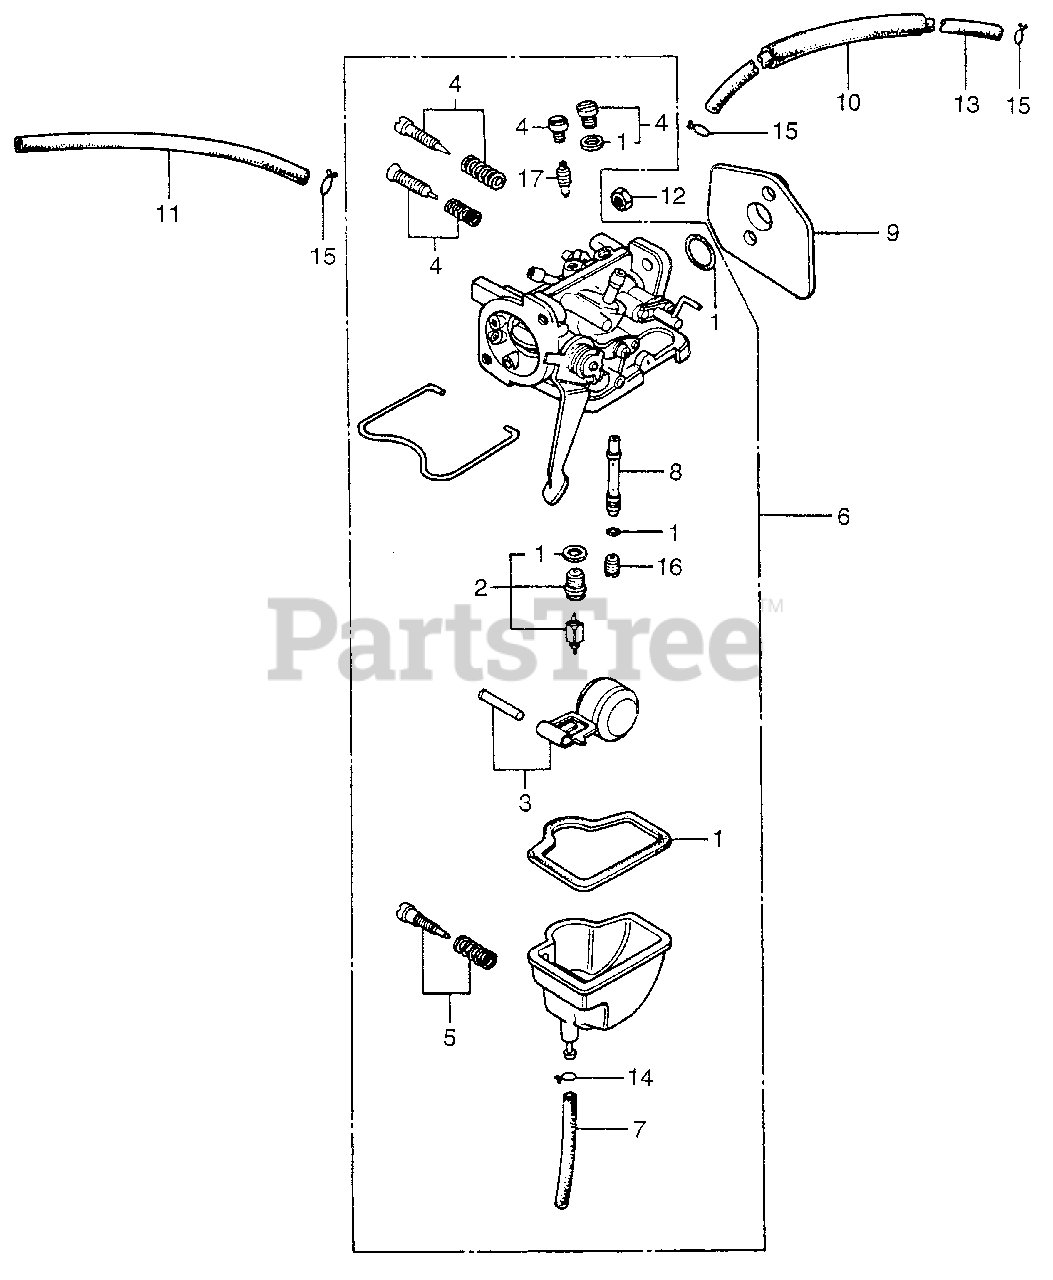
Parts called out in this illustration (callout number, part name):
1	GASKET SET
2	VALVE SET, FLOAT
4	SCREW SET (NOT AVAILABLE)
5	SCREW SET, DRAIN (NOT AVAILABLE)
6	CARBURETOR ASSY. (NOT AVAILABLE)
7	PIPE, RUBBER (2.5X7X60) (NOT AVAILABLE)
8	NOZZLE, MAIN (NOT AVAILABLE)
9	INSULATOR, CARBURETOR (NOT AVAILABLE)
10	RUBBER, SUPPORTER
11	TUBE, CARBURETOR OVERFLOW (NOT AVAILABLE)
12	NUT, HEX. (5MM)
13	BULK HOSE, FUEL (4.5X3000) (4.5X135)
14	CLIP, TUBE (B8)
15	CLIP, TUBE (B6.5)
16	JET, MAIN (#42)
16	JET, MAIN (#45)
16	JET, MAIN (#48)
16	JET, MAIN (#50)
16	JET, MAIN (#52)
17	JET, PILOT (#32)
17	JET, PILOT (#38) (NOT AVAILABLE)
17	JET, PILOT (#40)
17	JET, PILOT (#42)
